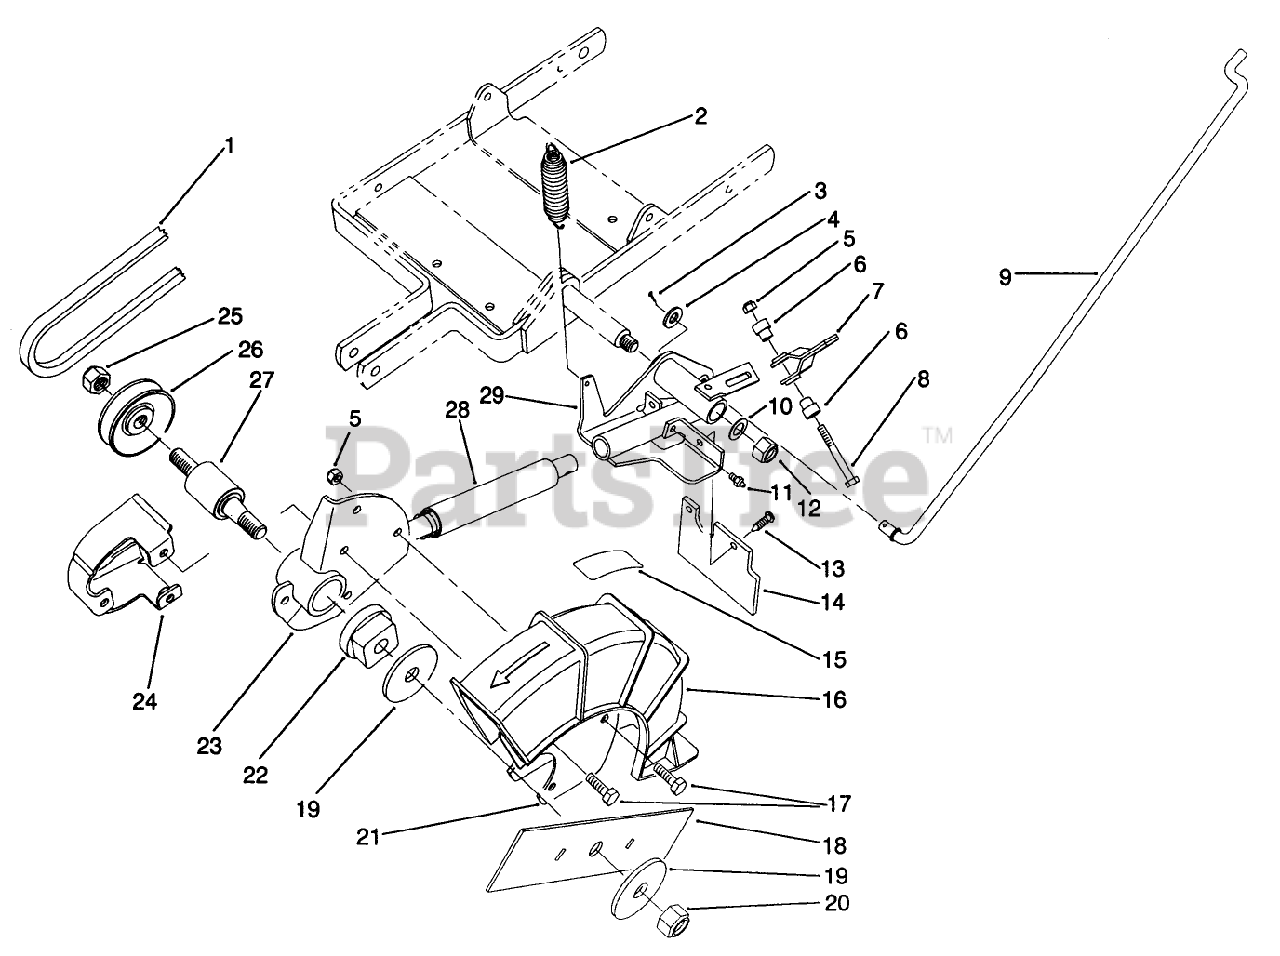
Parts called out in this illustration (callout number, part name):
2	EXT. SPRING
3	PIN-COTTER
4	WASHER-FLAT
5	NUT-LOCK, NI
7	LEVER WA *
8	SCREW-HH
9	LOWER CONTROL ROD *
10	WASHER-PLAIN
11	FITTING-GREASE
12	NUT-LOCK, NI
14	RUBBER GUARD
15	DECAL-BLADE
17	SCREW-HWHTF
18	9" EDGER BLADE*
19	WASHER-LARGE
20	NUT-HEX
23	HUB ASM *
25	NUT-LOCK, NI
28	SPRING & BELLOW ASM
29	PIVOT ARM WA *
